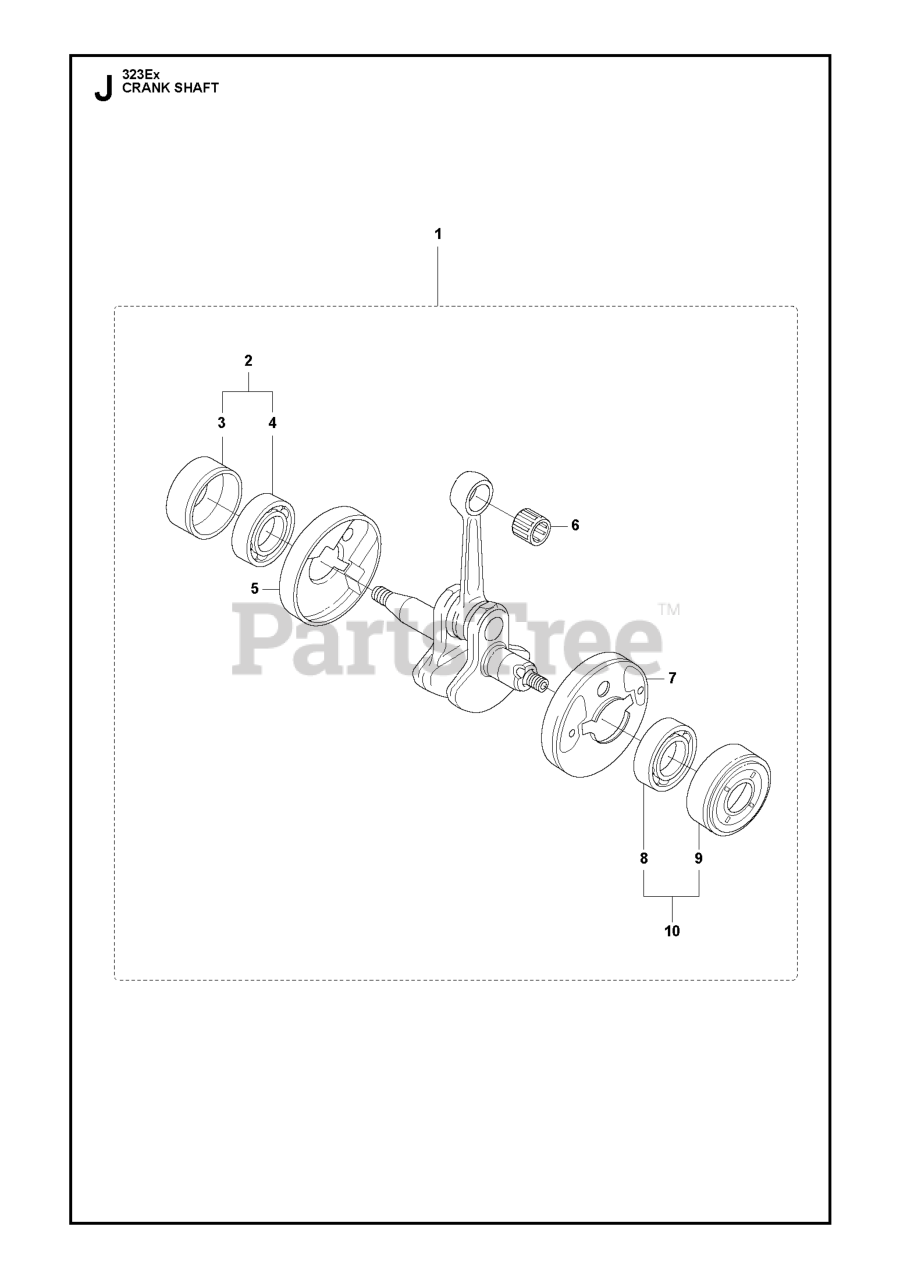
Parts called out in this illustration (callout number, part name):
1	CRANKSHAFT
2	BEARING W/ HOLDER
3	HOLDER
4	BALL BEARING
8	BALL BEARING
9	HOLDER
10	BEARING W/ HOLDER
